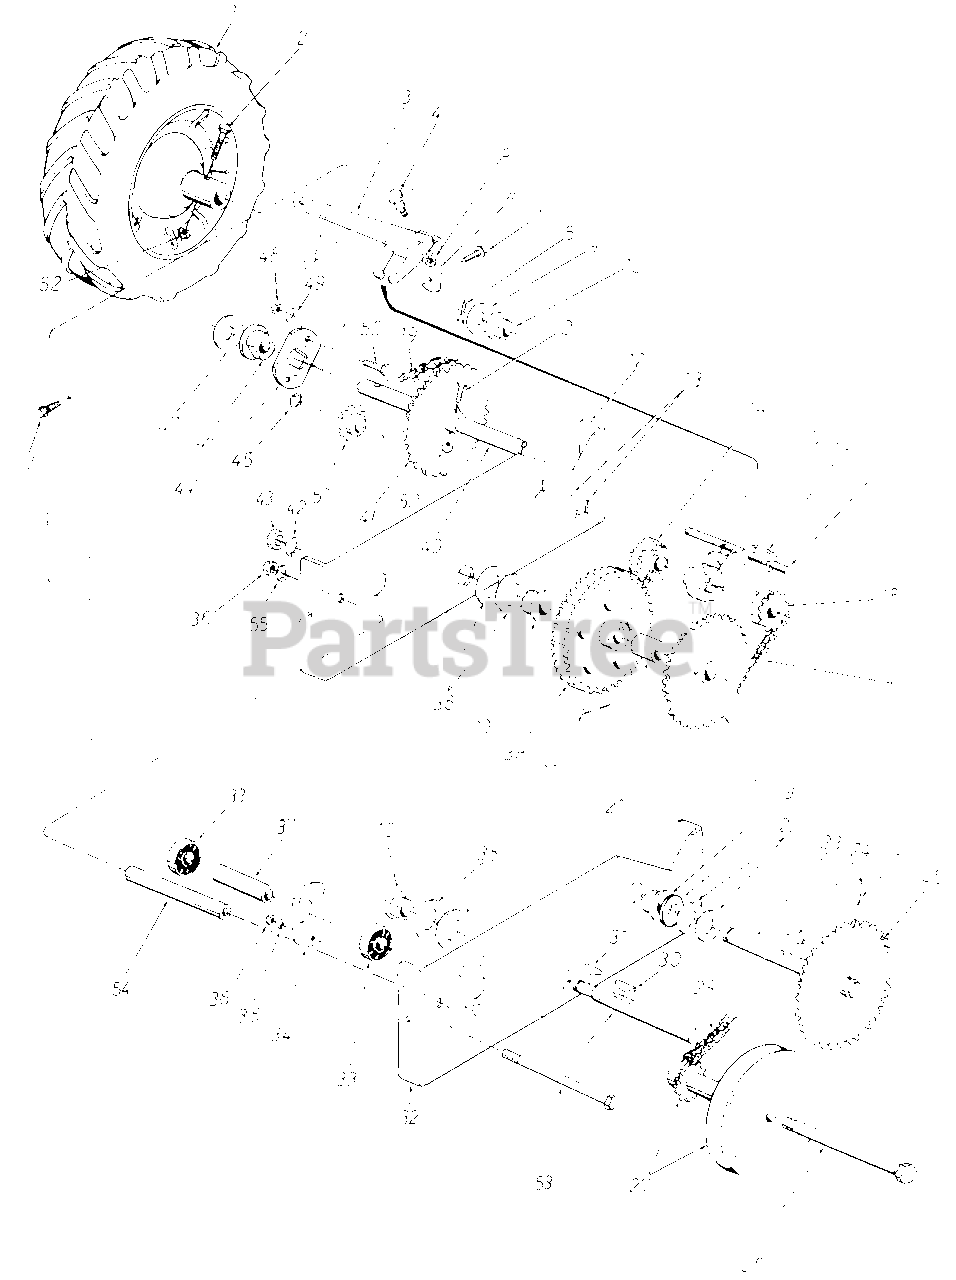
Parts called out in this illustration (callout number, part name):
1	Wheel Ass'y. - Comp. 10.0 x 2.75 - R.H.
2	Hex Scr. 5/16-24 x 1.75" Lg. H.T.
3	Shifting Bracket
4	Shld. Scr. .438" Dia. x .180 Lg.
5	Hex Cent. L-Nut 5/16-18
6	Shifting Bracket Support
7	Hex Wash. Hd. Self-Tap Scr. 5/16-24 x .50
8	Cotter Pin 3/32 Dia. x 1.00" Lg.
9	Fl-Wash. .64 I.D. x 1.25 O.D. x .060
10	Hex Flange Brg. .63 I.D.
11	H-Spring Pin Spiral 1/4" Dia. x 1.50 Lg.
12	Drive Housing Bracket - R.H.
13	Internal Cotter Pin 3/8" Dia.
14	Spur Gear - 21 Teeth
15	Clutch Collar
16	Shifting Yoke
18	Sprocket - 10 Teeth
19	#41 Chain - 1/2" Pitch x 33 Links
20	28 Teeth - Sprocket Hub Ass'y.
21	Spacer - .62 I.D. x .88 O.D. x 1.030
22	Fl-Wash. .64 I.D. x 1.25 O.D. x .100
23	Shifting Shaft
24	Hi-Pro Key 3/16 x 3/4" Dia. x 1.062
25	32 Teeth Sprocket Hub Ass'y.
26	Hex Scr. 1/2-20 x 5.50" Lg.
27	5.25" O.D. Pulley with 9 Teeth Sprocket
29	#41 Chain 1/2 Pitch x 47 Links
30	Hi-Pro Key - 3/16 x 3/4" Dia.
31	Hi-Pro Key - 3/32 x 5/8" Dia.
32	Drive Housing Bracket Ass'y. - L.H.
33	Ball Bearing .500 I.D. x 1.38 O.D. x .438
34	Bearing Housing
35	L-Wash. 1/4 Scr.
36	Hex Nut 1/4-20 Thd.
37	Spacer - .52 I.D. x .62 O.D. x 2.69
38	Fl-Wash. 1.06 I.D. x 1.75 O.D. x .100
39	Spur Gear - 62 Teeth
40	Wheel Axle
41	28 Teeth - Sprocket Hub Ass'y.
42	L-Wash. for 1/2 Scr.
43	Hex Ins. Jam L-Nut 1/2-20 Thd.
44	Bearing Plate
45	E-Ring for .500" Dia. Shaft
46	Flange Bearing w/Flats .753 I.D.
47	Fl-Wash. .81 I.D. x 1.25 O.D. x .060
48	Hex Nut 5/16-18 Thd.
49	L-Wash. 5/16" Scr.
50	Carriage Bolt 5/16-18 x .75" Lg.
51	8 Teeth Sprocket #41 Chain
52	Hex Jam L-Nut 5/16-24 Thd.
53	Hex Bolt 5/16-18 x 4.0" Lg.
54	Spacer 3.25" Lg.
55	L-Wash. 5/16" I.D.
